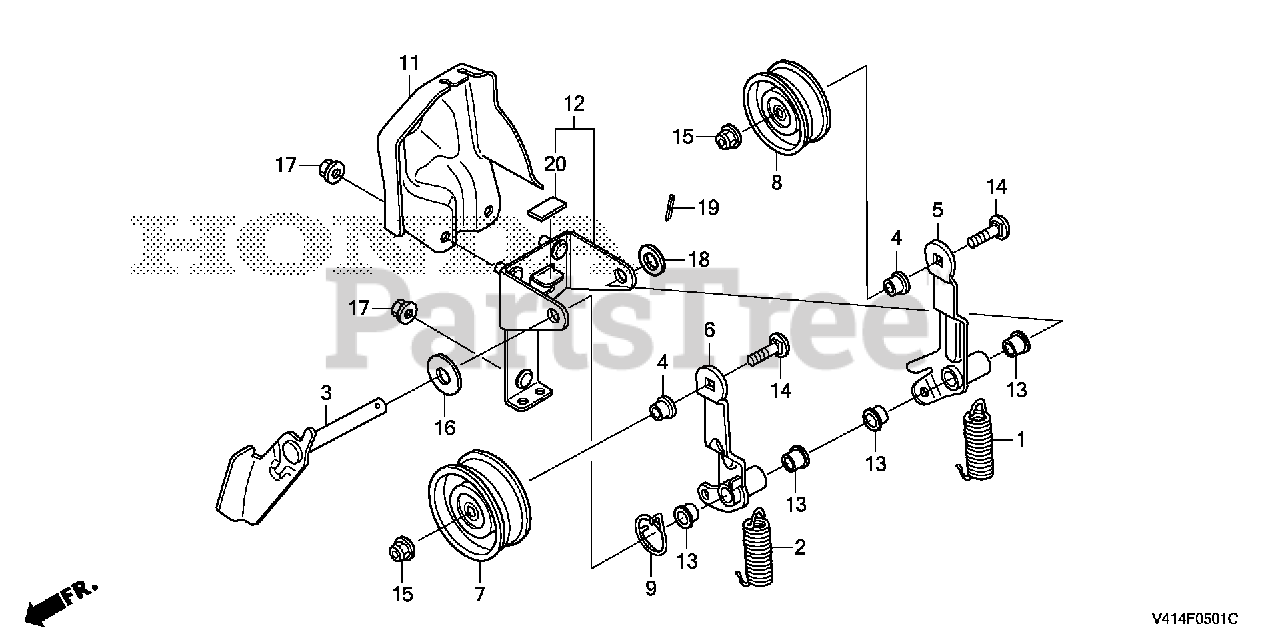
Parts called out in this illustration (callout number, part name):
1	SPRING, WHEEL TENSIONER RETURN
2	SPRING, AUGER TENSIONER RETURN
3	ARM, AUGER BRAKE
4	COLLAR, ROLLER
5	ARM, WHEEL TENSION
6	ARM, AUGER TENSIONER
7	ROLLER, TENSIONER
8	ROLLER, TENSIONER
9	SPRING, BRAKE ARM (NOT AVAILABLE)
10	RUBBER, STOPPER
11	HOLDER, WIRE
12	BRACKET, TENSION ARM
13	BUSH, CHANGE ARM
14	BOLT, CARRIAGE (8X28)
15	NUT, FLANGE (M8X1.25) (SELF-LOCK)
16	WASHER, BRAKE ARM
17	NUT, FLANGE (8MM)
18	WASHER, PLAIN (12MM)
19	PIN, SPLIT (3.0X18)
20	RUBBER, STOPPER
